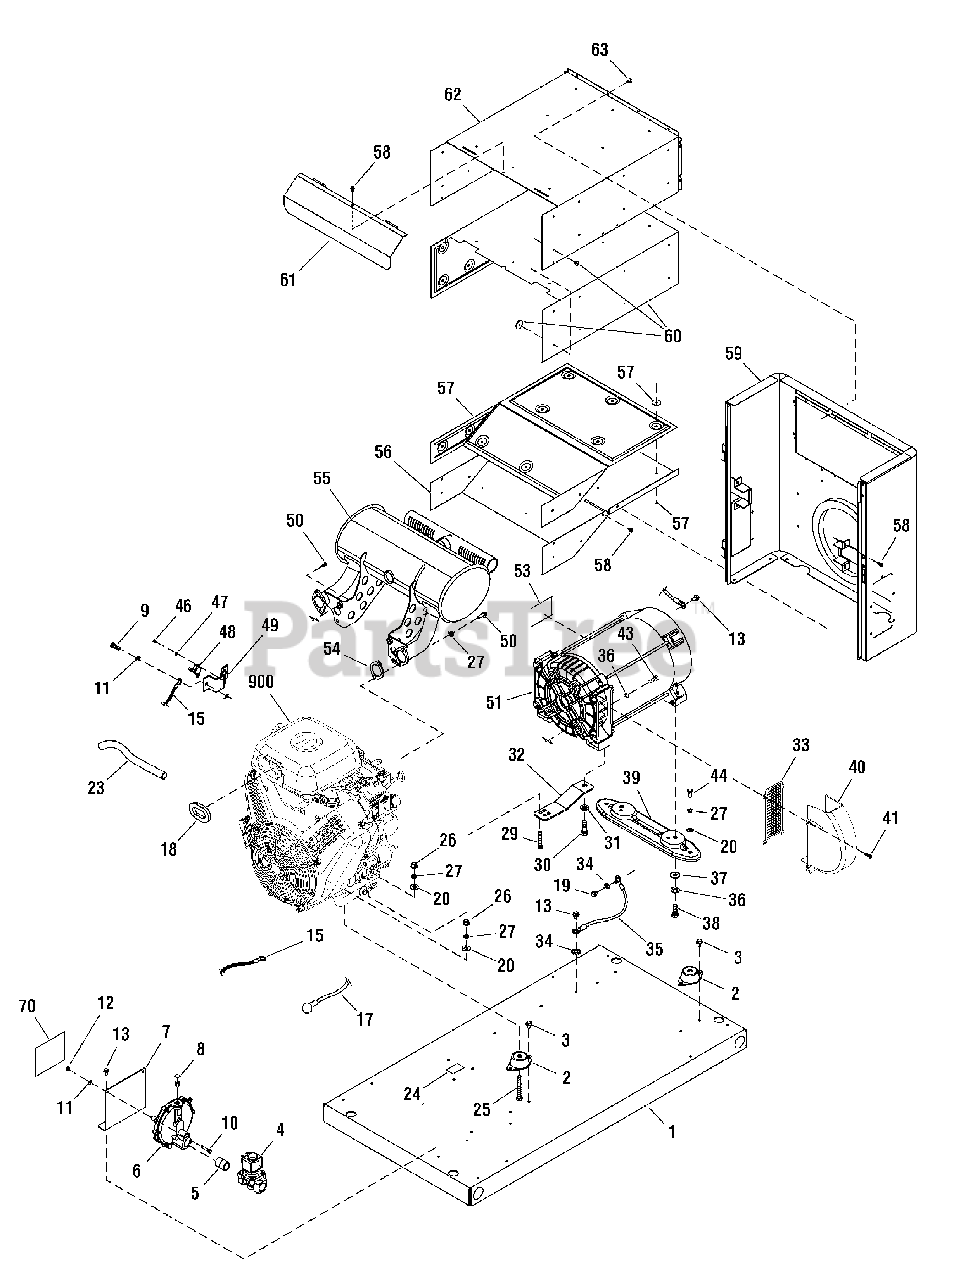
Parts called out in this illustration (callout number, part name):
1	BASE
2	MOUNT, Vibration
4	SOLENOID, Gas Fuel
6	REGULATOR, NG/LPG
7	BRACKET
9	* CAPSCREW, Hex Head, M6-1.0 x 16
10	* CAPSCREW, Hex Head, M6-1.0 x 30
11	* WASHER, Lock, 1/4
12	* NUT, M6-1.0
13	BOLT
15	CABLE, Battery, Black
17	CABLE, Battery, Red
18	TUBE
20	* WASHER, Flat, 5/16 - M8
23	HOSE, Oil Drain
24	DECAL, Oil Drain
25	* CAPSCREW, Hex Head, 5/16-18 x 2-1/2
26	* NUT, 5/16-18
27	* WASHER, Lock, 5/16 - M8
29	* CAPSCREW, Hex Head, 5/16-18 x 2
30	* CAPSCREW, Hex Head, M12-1.75 x 35
31	* WASHER, M12
32	SUPPORT, Engine
34	* WASHER, Shakeproof, M6-1/4
36	* WASHER, Lock, 3/8
37	* WASHER, Flat, 3/8-M10
38	* CAPSCREW, Hex Head, 3/8-16 x 1
39	SUPPORT, Alternator
43	* CAPSCREW, Socket Head, 3/8-16 x 1-1/4
44	* CAPSCREW, Hex Head, 5/16-18 x 3/4
46	* SCREW, Phillips Head,4-40 x 0.19
47	* WASHER, Lock, #4
49	PLATE, Temp Switch
50	SCREW
51	ALTERNATOR
53	DECAL
59	BULKHEAD, Alternator
62	BOX, Muffler Top
900	** ENGINE
